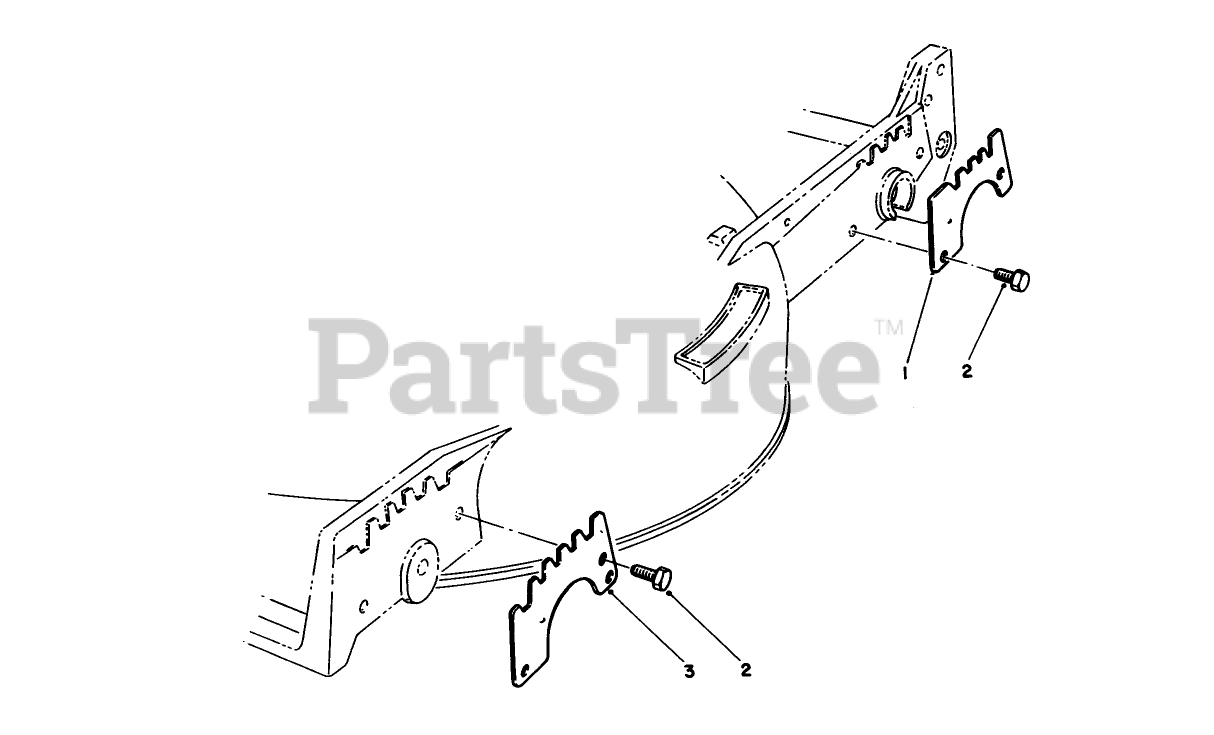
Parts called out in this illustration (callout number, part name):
1	WEAR PLATE,REAR
2	SCREW-HWH
3	WEAR PLATE
